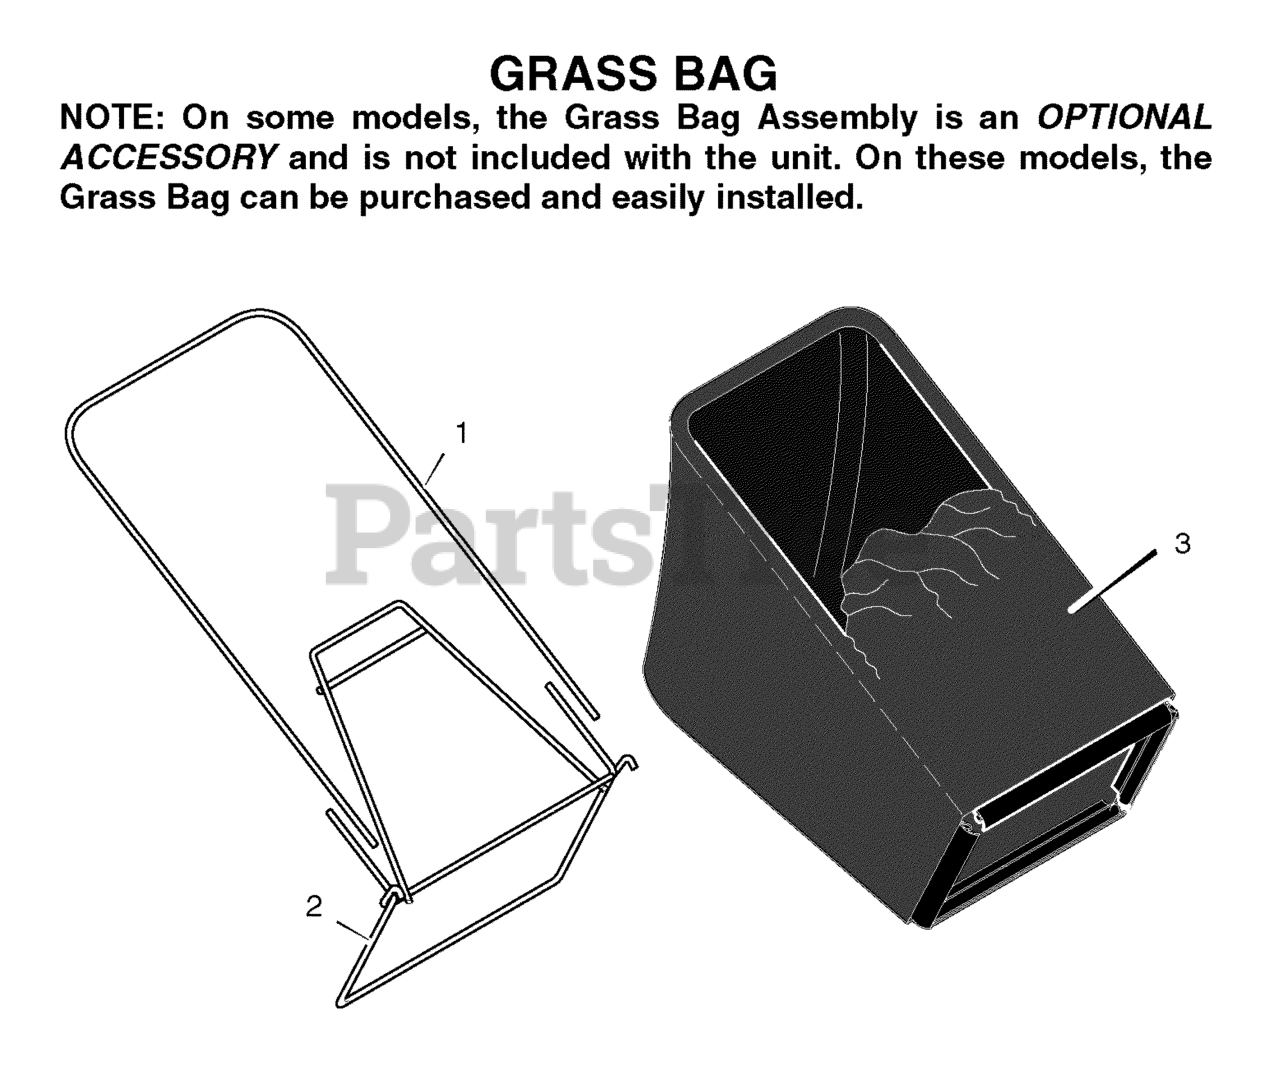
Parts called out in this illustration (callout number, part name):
1	Tube, Bag
2	Frame Assembly
3	Bag, Cloth - Black
